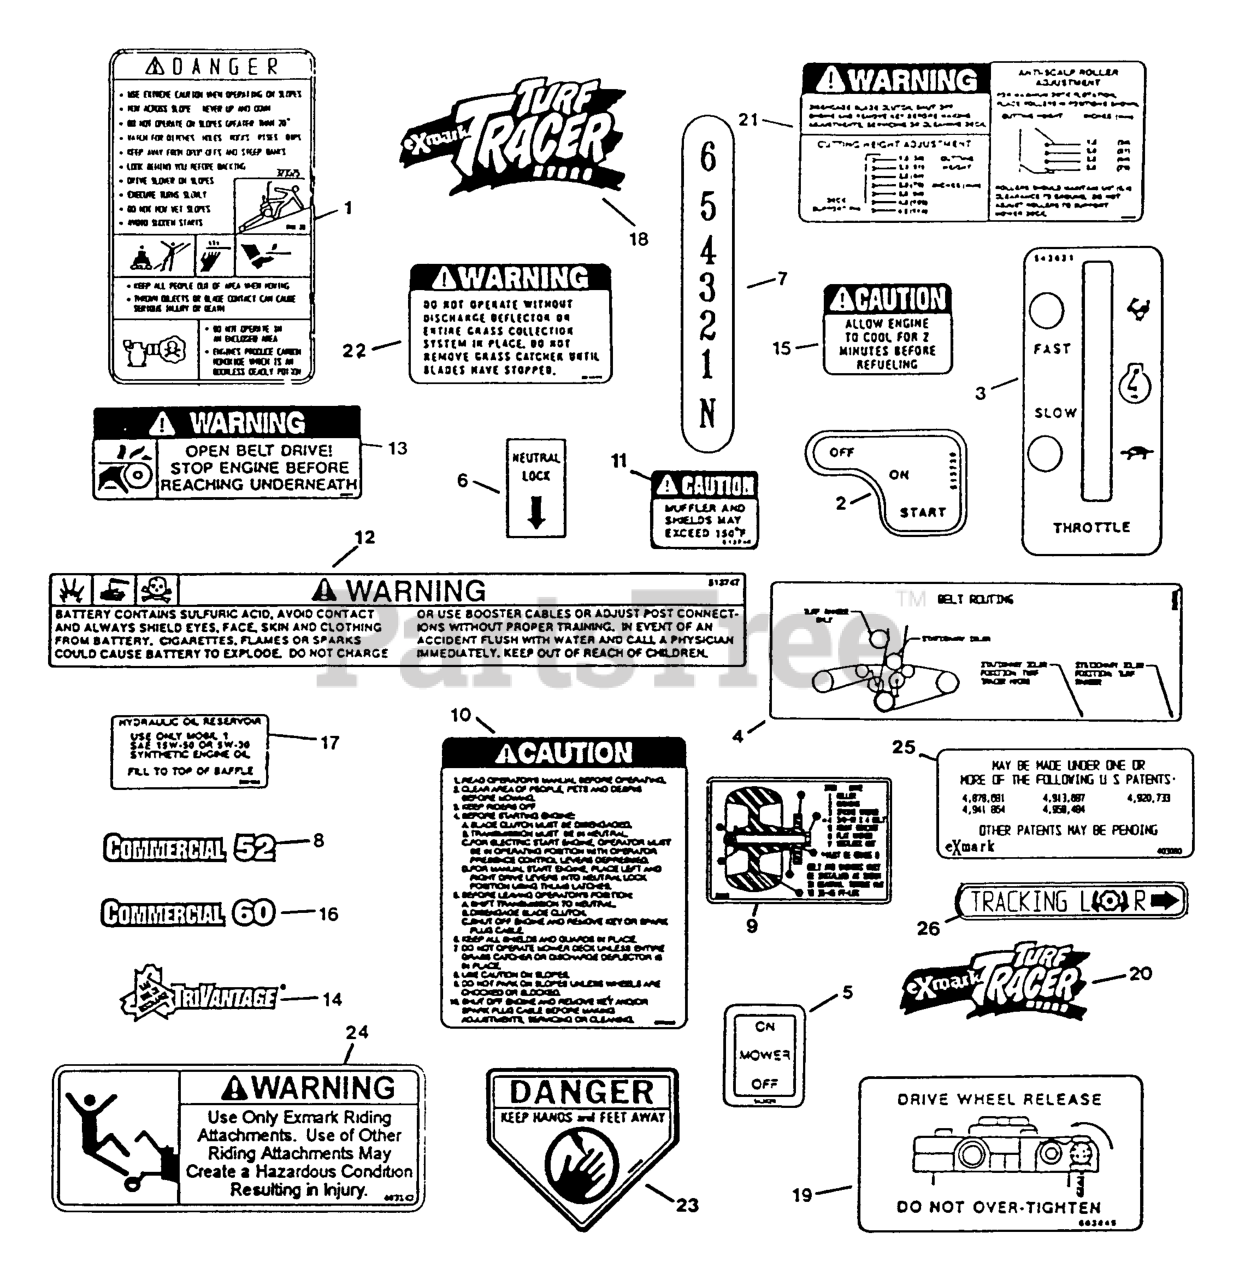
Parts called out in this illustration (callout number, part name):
4	DECAL,BELT ROUTING
5	DECAL-MOWER SWITCH
6	DECAL,NEUTRAL LOCK
7	DECAL - SHIFTER
8	DECAL,COMMERCIAL 52
9	DECAL,ROLLER MOUNTING
12	DECAL-BATTERY
13	DECAL,BELT DRIVE
16	DECAL,COMMERCIAL 60
17	DECAL,HYD TANK
19	DECAL,DRIVE RELEASE
22	DECAL-WARNING, DISCHARGE
23	DECAL-DANGER
24	DECAL,SULKY WARNING
26	DECAL,TRACKING ADJUST
